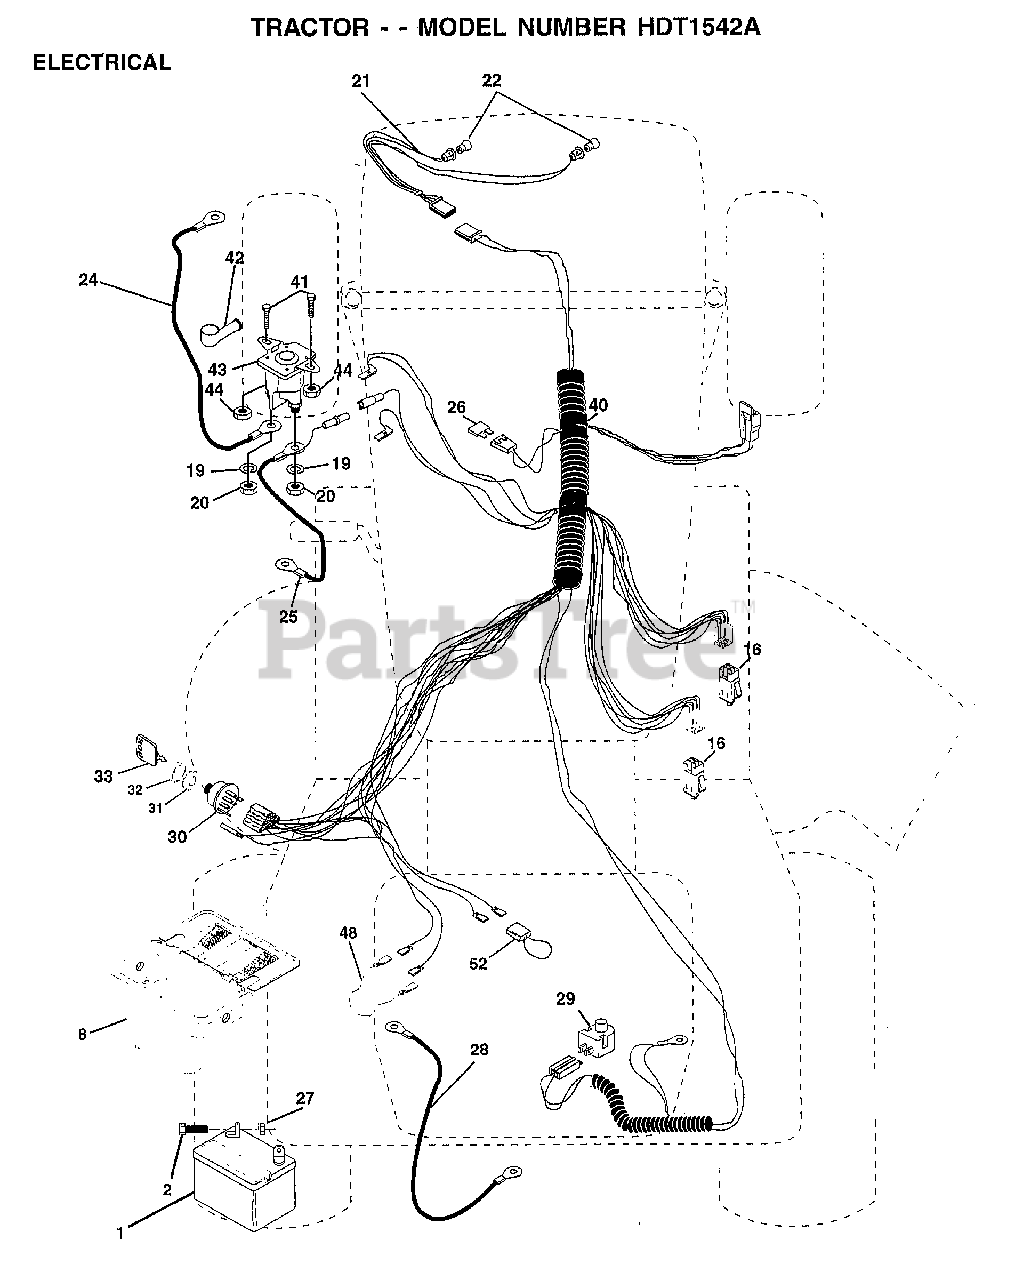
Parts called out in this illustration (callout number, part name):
2	BOLT LT
8	"CASE,BATTERY.MECH"
16	SWITCH INTERLOCK
20	NUT
21	HARNESS.ASM.LIGHT W/4152J
22	HEADLAMP BULB
24	CABLE ASM.
25	CABLE.BTRY.6GA.RD
26	FUSE.15 AMP
27	NUT
28	CABLE T
29	SWITCH SEAT
30	SWITCH IGN 4POS
31	NUT IGNITION
32	COVER KEY SWITCH
33	KEY
40	HARNESS.IGNITION
41	BOLT HXHD FIN
44	NUT HXKEP 1/4X20
48	ADAPTER AMMETER
52	PROTECTION LOOP
